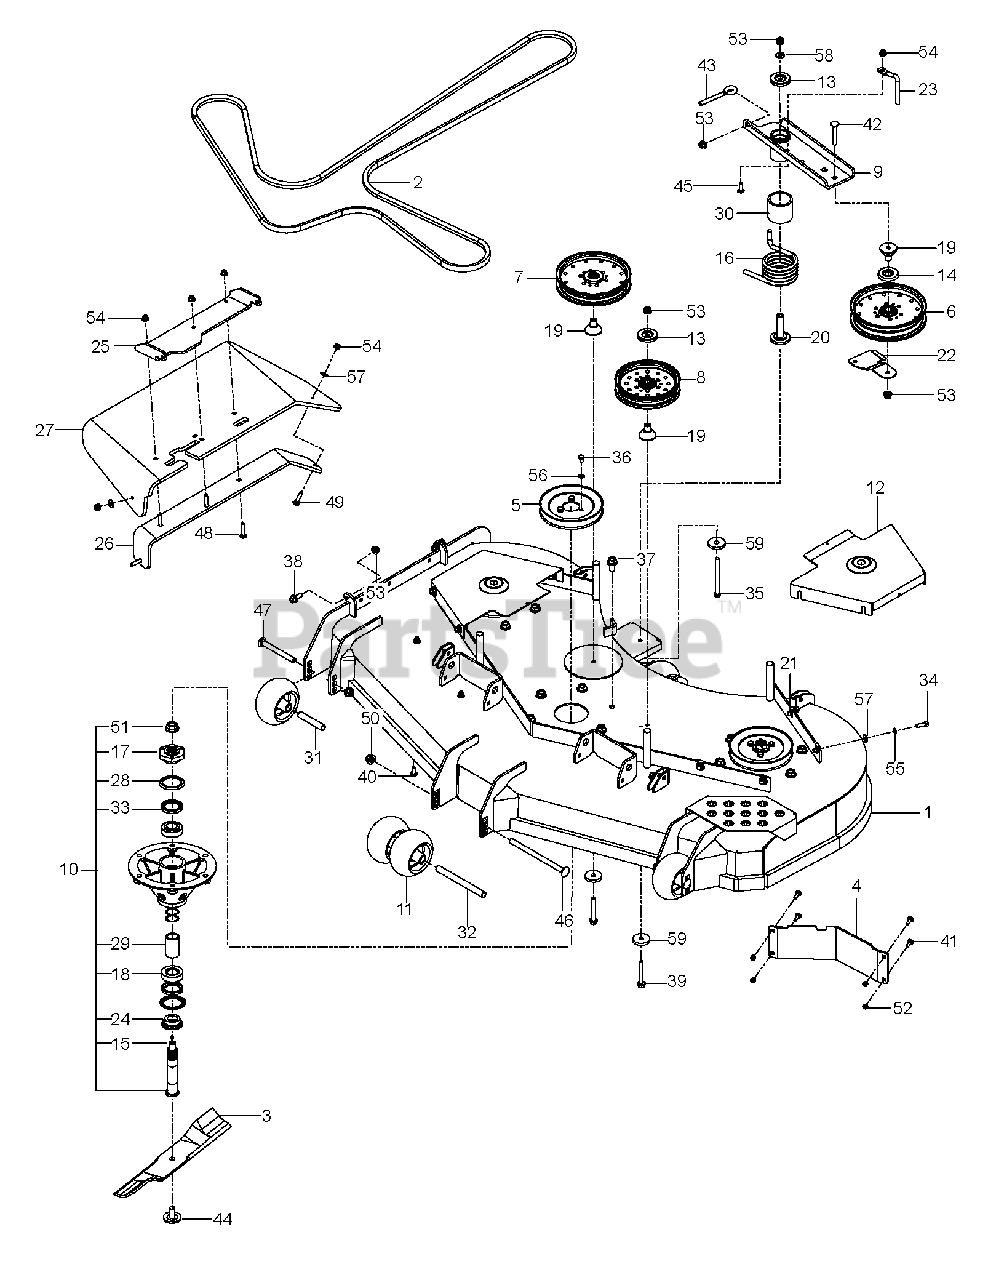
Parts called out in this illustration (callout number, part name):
1	DECK.W/DECALS.PZ.60"
2	BELT, "5V", 176"
3	BLADE - HEAVY DUTY 21"
4	BAFFLE, DIVERTER 54"/60" LH
5	PULLEY - 6.57
6	PULLEY - IDLER 7"
7	PULLEY - 7" NARROW
8	PULLEY IDLER, 6" NARROW
9	ASSY, IDLER ARM, PZ
10	SPINDLE.ASM.10".IRON.1/8-27
11	ROLLER, GAUGE .635 BORN
12	SHIELD,BELT, 60" ORANGE
13	DUST SHIELD
14	SHIELD, DUST
15	ZERK
16	SPRING, TORSION, IDLER
18	BEARING - 206KRR8
19	BEARING, IDLER ARM
20	BEARING, IDLER PIVOT
21	U-CLIP 5/16-18 NUT RETAINER
22	BELT.GUIDE.BLACK
23	BELT KEEPER
25	BRKT - CHUTE MTG BLACK
26	BRKT, CHUTE SUPPORT BLACK
27	CHUTE, DISCHARGE 48-52
28	SEAL V-RING 55MM
30	SPACER, IDLER PIVOT
31	TUBE, ROLLER AXLE
32	TUBE, ROLLER AXLE LONG
33	SEAL SHAFT
34	HCS 5/16C X 1
35	HCS 3/8-16 X 4-1/2 GR 8 ZD
36	HCS 5/16-18 X 1/2 GR 5 ZD
37	HHFS 1/2-13 X 1 GR5 ZD
38	HHFS 3/8-16 X 1 GRD 5 ZD
39	HHFS 3/8-16 X 2 3/4
40	HHFS 5/16-18 X 3/4
41	1/4-20X3/4 CARR BLT
42	CARRIAGE BOLT 3/8-16 X
43	EYE BOLT, 3/8 X 4"
44	BLADE BOLT/WASHER
45	RHSSNB 5/16C X 1.0
46	RHSNB 1/2-13 X 8 GR5 ZD
47	RHSNB 1/2-13 X 4.75 GR5 ZD
48	RHSNB 5/16-18 X 1-1/2 GR 5 ZD
49	BOLT, CARRIAGE 5/16X1-1/4
50	NUT, 1/2-13 HEX FLG NYLOC ZD
51	NUT FLANGE 3/4-16
52	RP_NUT 1/4-20 NYLOC
53	NUT 3/8-16 HEX FLG NYLOC ZD
54	5/16-18 NYLOC FLANGE NUT
55	WASH.5/16.SLW.ZD
56	WASH 5/16 DISC SPRING ZD
57	WASHER 5/16 FLAT
58	WASHER, 3/8 THICK
59	SPINDLE WASHER
